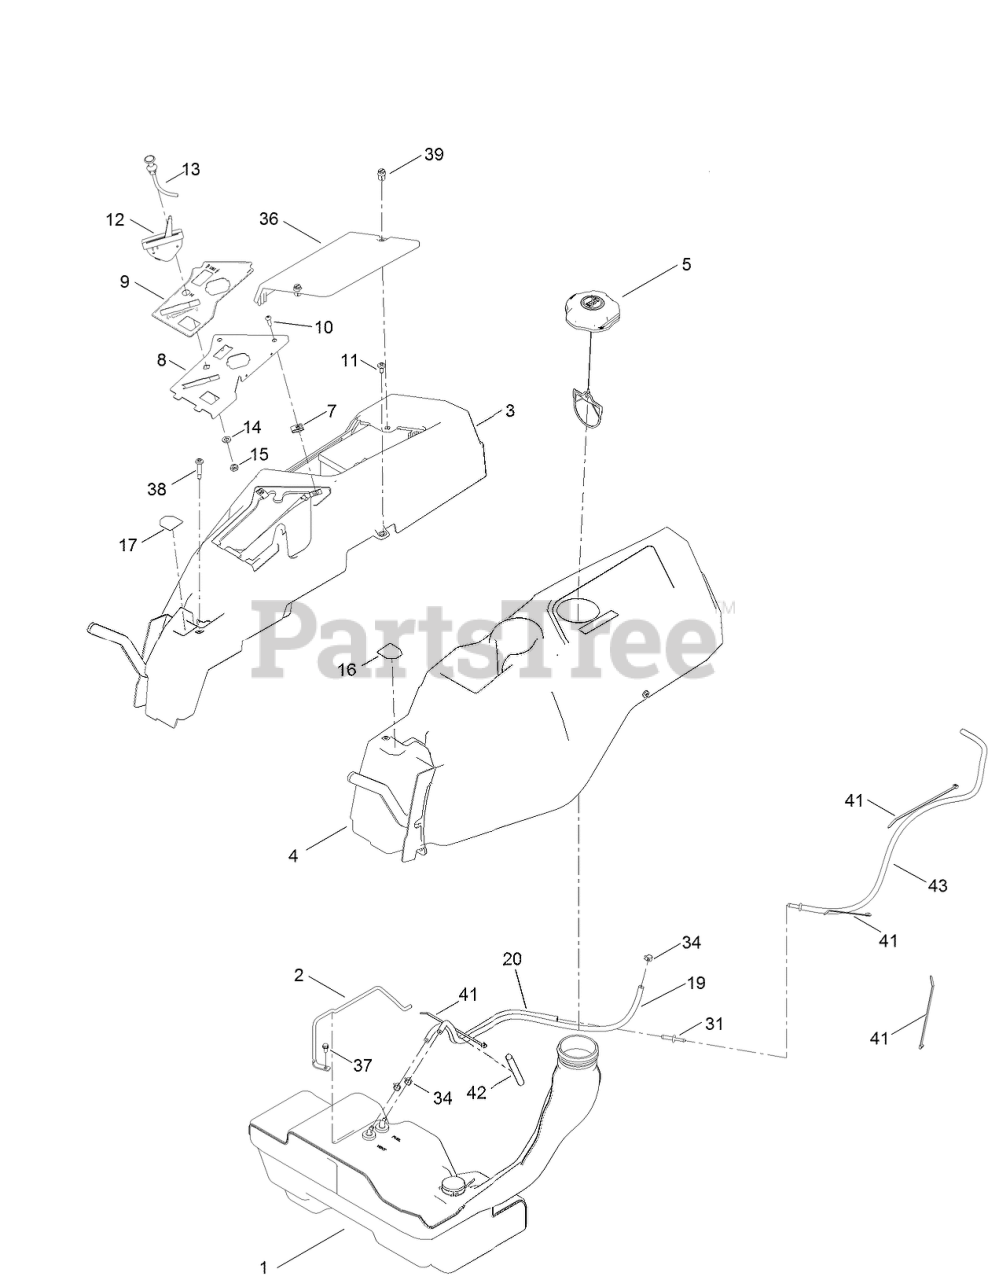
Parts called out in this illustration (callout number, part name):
1	FUEL TANK ASM
2	ROD-HOLD DOWN
3	POD-RH
4	POD-LH
5	CAP-FUEL, RATCHETING
8	PANEL-CONTROL
9	DECAL-PANEL, CONTROL
10	SCREW-PRH
11	SCREW-SHOULDER
12	CABLE-THROTTLE
13	CABLE-CHOKE
14	WASHER-LOCK
15	NUT-HJ
16	DECAL-LEVER, CONTROL (LH)
17	DECAL-LEVER, CONTROL (RH)
19	HOSE-FUEL
20	HOSE-FUEL
31	ADAPTOR-ORIFICE
34	CLAMP-HOSE
36	COVER-BATTERY
37	SCREW-HWH
38	SCREW-SHOULDER
39	FASTENER
41	TIE-CABLE
42	SLEEVE-FUEL LINE PROTECTOR
43	HOSE-FUEL
